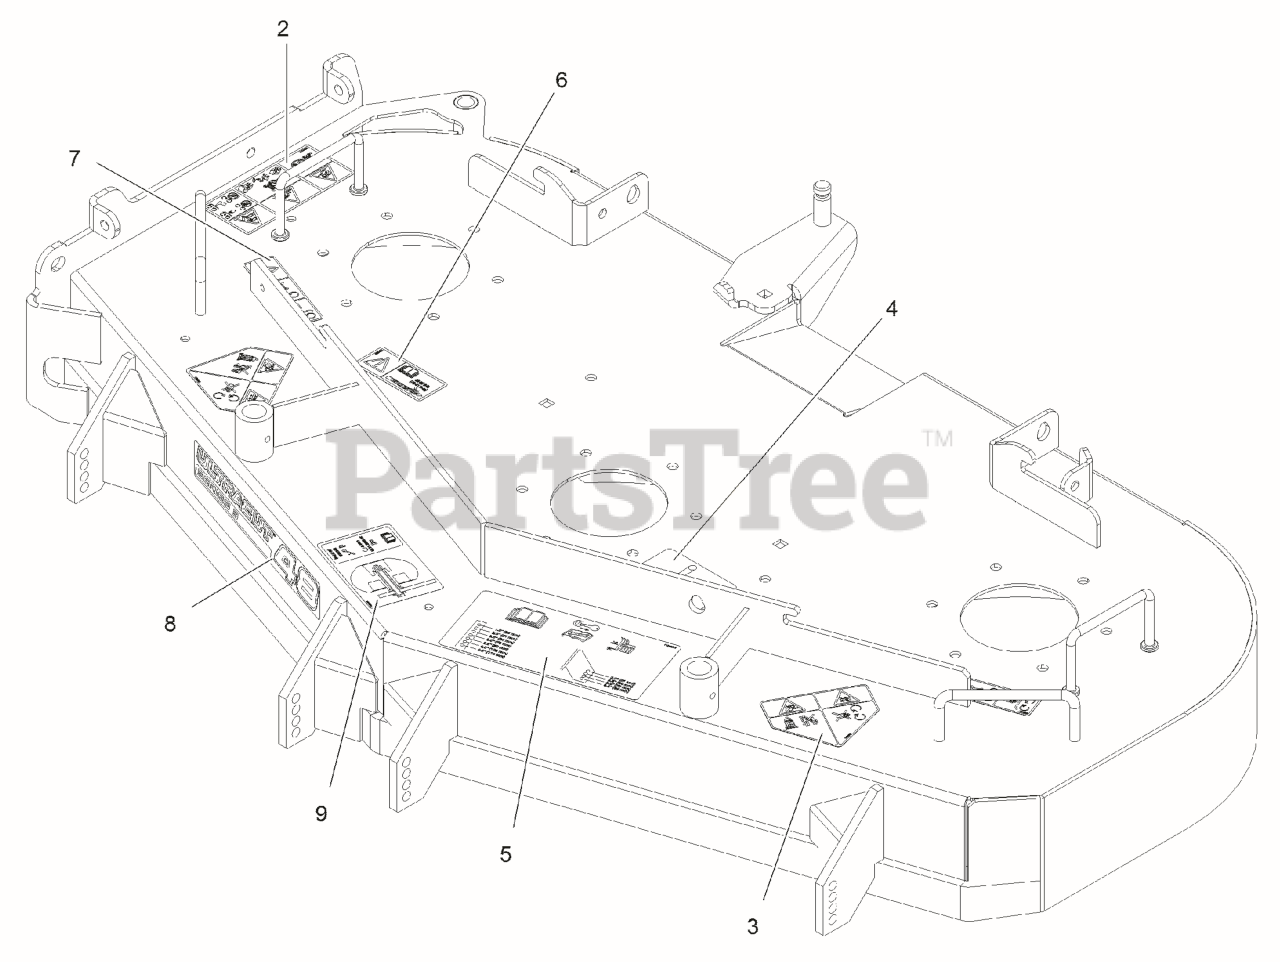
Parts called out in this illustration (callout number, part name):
2	DECAL-WARNING, BAGGER
3	DECAL-DANGER
4	DECAL-BELT ROUTING
5	DECAL-ANTI-SCALP
6	DECAL-BOLT TORQUE
7	DECAL-COVER, MISSING
8	DECAL-ULTRACUT 48 SERIES
9	DECAL-ROLLER MOUNTING
